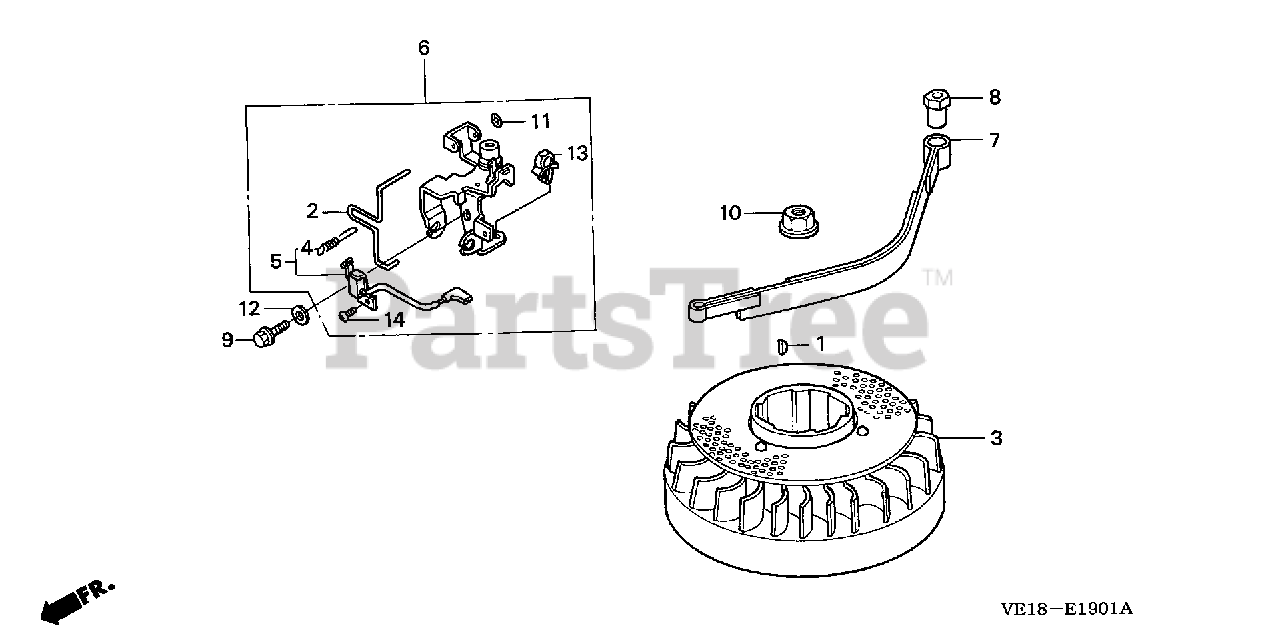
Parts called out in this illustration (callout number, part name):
1	KEY, SPECIAL WOODRUFF (25X18)
2	ROD, GOVERNOR ARM RETURN
3	FLYWHEEL ASSY.
4	SPRING, SWITCH CONTROL
5	SWITCH ASSY., ENGINE STOP (BRAKE)
6	LEVER ASSY., BRAKE
8	COLLAR, BRAKE SHAFT
9	BOLT, FLANGE (6X14) (CT200)
10	NUT, SPECIAL (14MM)
11	NUT, SPEED
12	WASHER, SEALING (12MM)
12	WASHER, SEALING (6.2X12X1.2)
13	CLIP, ENGINE STOP SWITCH CORD
14	SCREW, PAN (4X6)
